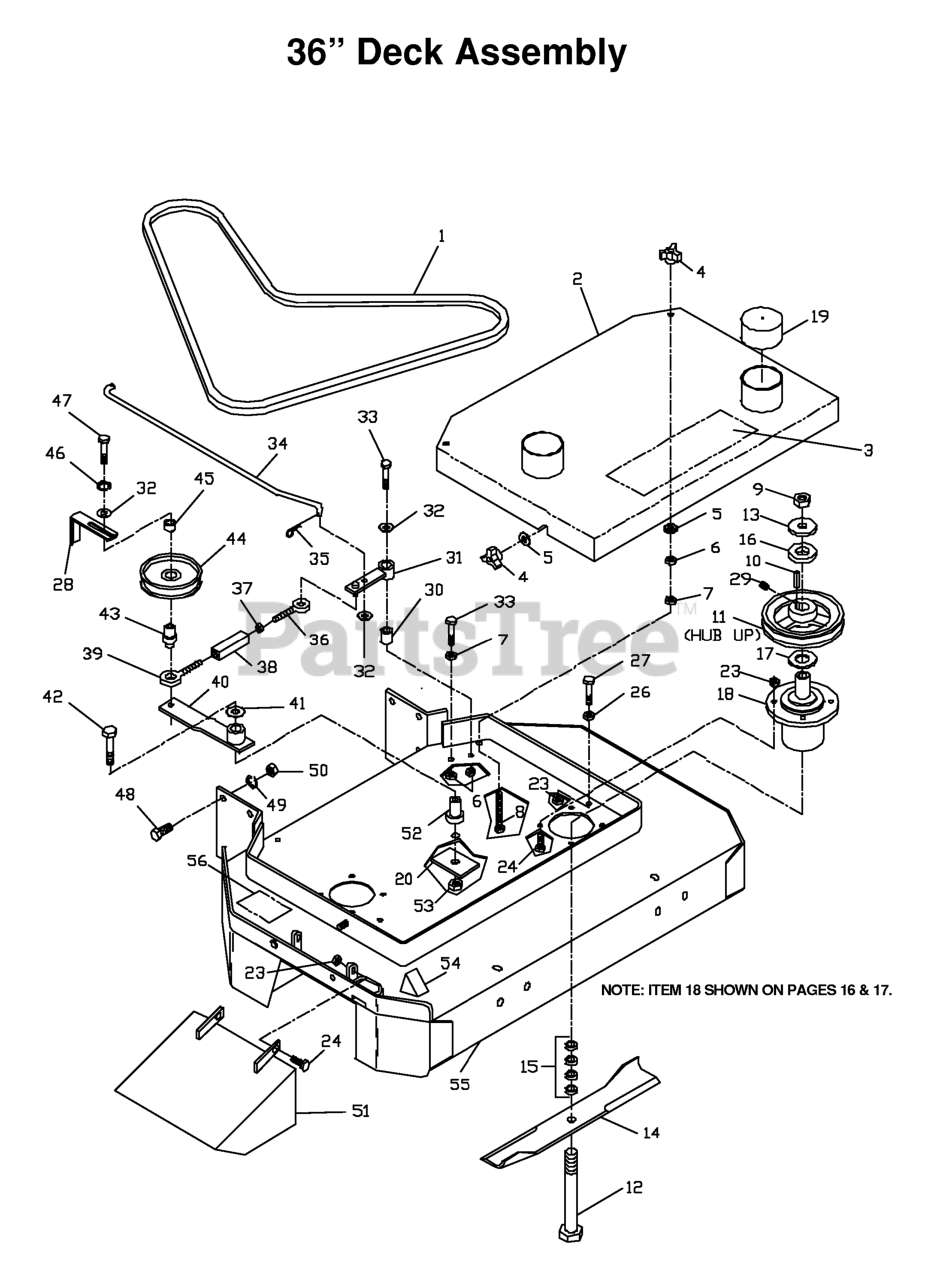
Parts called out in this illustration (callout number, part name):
1	BELT, DECK, 36"
2	BELT SHIELD ORANGE 36"
3	DECAL, HUSQ 12" BLUE
4	KNOB, THREE PRONG
5	WASHER, 3/8 SEALING
6	NUT 3/8C CENTERBLOCK
7	NUT 3/8C WHIZ
8	TAPBOLT 3/8C X 4 1/2
9	NUT 5/8F HEX
10	KEY 1/4 SQ X 1 1/8
11	PULLEY W/SETSCREWS
12	HCS 5/8F X 8 1/2
13	SPINDLE WASHER
14	BLADE OEM 18"
15	BLADE SPACERS
17	MACHINERY BUSHING 10 GA.
18	HOUSING ASSEMBLY
23	NUT 5/16C CENTERLOCK
24	HCS 5/16C X 1
26	NUT 5/16C WHIZ
27	HCS 5/16 X 3
29	SET SCREW 5/16 NYLOC
30	BUSHING, SLEEVE
31	ENGAGEMENT ARM
32	WASHER 3/8 FLAT
33	HCS 3/8C X 2 1/4
34	BLADE ROD 36"
35	HAIRPIN #2
36	EYEBOLT, RH
37	NUT 5/16C HEX
38	TURNBUCKLE
39	EYEBOLT, LH
40	ARM WELDMENT
41	WASHER 1/2 FLAT
42	HCS 1/2C X 2 3/4
43	EYEBOLT PIVOT
44	IDLER PULLEY
46	SLW 3/8 STD
47	HCS 3/8C X 2 1/2
48	HCS 7/16C X 1 1/2
49	WASHER 7/16 LOCK
50	NUT 7/16C HEX
51	DEFLECTOR CHUTE
52	IDLER SPINDLE
53	NUT 1/2-13 HEX NYLOC ZD
54	DECAL, CPSC
55	DECK W/DECALS 36"
56	DECAL, EURO SEVERING
57	DECAL, NASCAR
